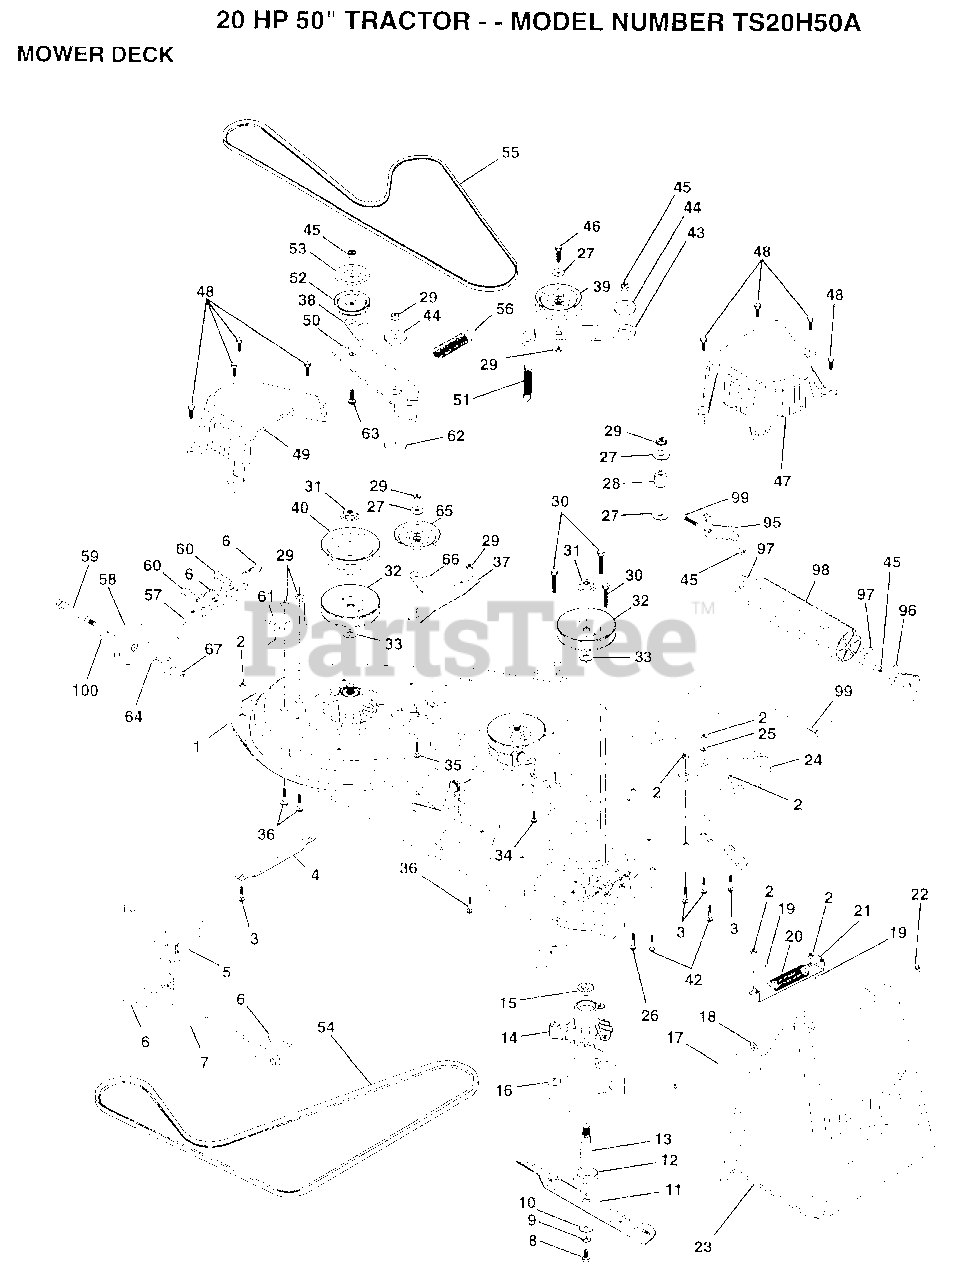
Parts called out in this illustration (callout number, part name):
1	DECK ASM MWR 50VT
2	NUT
4	RUNNER-LH M
5	BRKT.ASM.SW.44/50
8	BLADE BOLT
10	WASHER.HARD.BLADE
11	"BLADE.50"" HD"
12	BEARING.BALL
13	SHAFT.ASM.W/BRNG
14	HOUSING.MAND.44.V
15	BEARING
16	STRIPPER RND MWR
17	ROD-HINGE T
18	WASHER
19	CAP-SLEEVE LT
20	SPRING TORSION
21	BRKT DEFLECTOR
22	NUT PUSH M
23	DEFLECTOR
24	"RUNNER RH 50"" DK"
25	WASHER M
26	BOLT
27	WASHER
28	NUT
33	WASHER
34	BOLT.3/8-14X1.25
35	BOLT
36	BOLT D
37	STIFFENER.ARM.IDL
39	FLAT IDLER PULLEY
40	"PULLEY.DRIVEN.44"""
42	BOLT
43	"ARM.IDLER.SEC.44"""
44	SPACER RETAINER
47	"COVER.MAND.RH.44"""
48	SCREW.1/4-20X5/8
49	COVER.MANDREL.LH
50	ARM.IDLER.PRIMARY
51	"SPRING.SEC.44""VEN"
52	PULLEY.IDLER.VGRO
53	SHIELD.IDLER.44.V
54	BELT V PRIM 50
55	BELT.V.GDRIVE.95
56	SPRING.EXT.DECK.
57	BAR.ASM.GUAGE.WHL
58	WHEEL.GAGE.BLK.PL
59	BOLT M
60	PIN.CLEVIS
61	BRACKET.GUAGE.WHL
62	HARDENED WASHER
63	BOLT.3/8-16X1.50
64	WASHER
65	IDLER-FLAT T
67	LOCKNUT
97	WASHER
99	BOLT
100	WASHER
